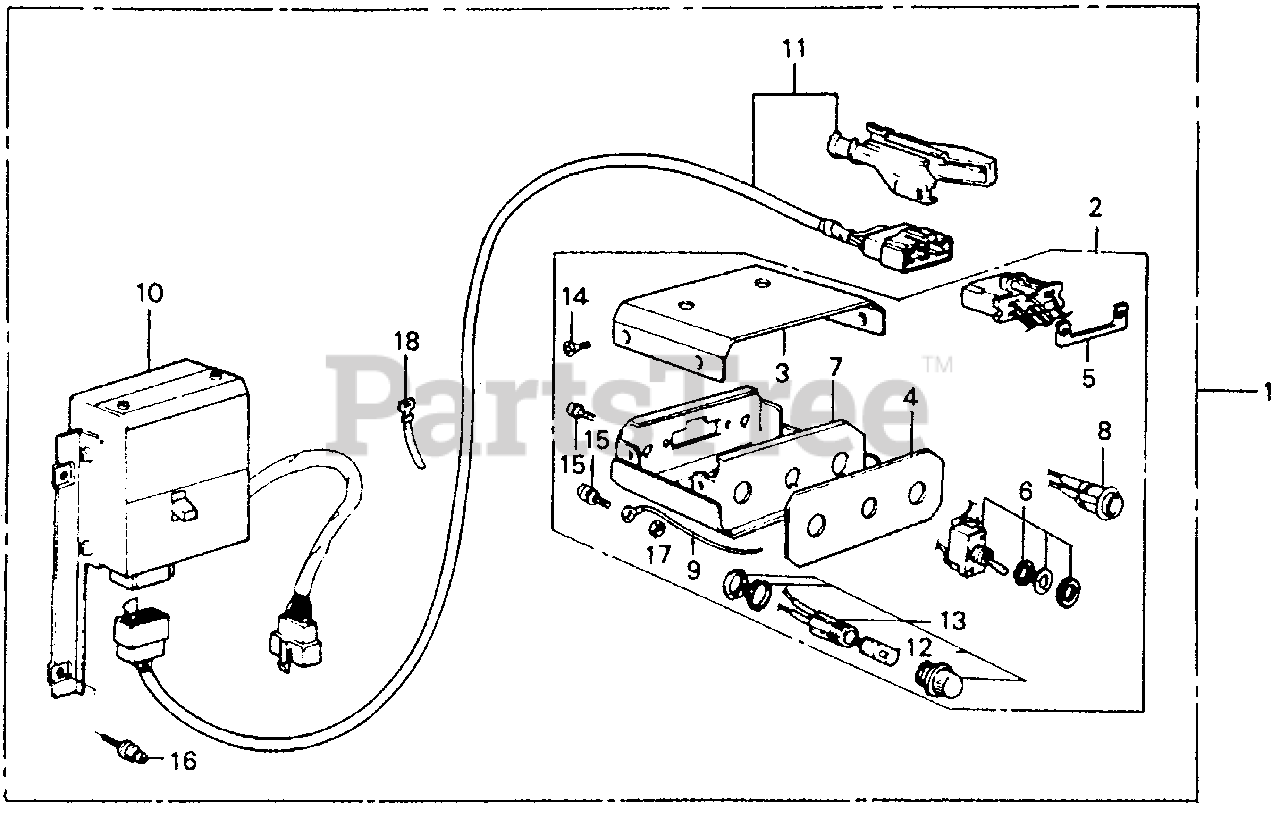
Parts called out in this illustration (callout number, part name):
1	CONTROL KIT, REMOTE
2	BOX ASSY., SWITCH *R8*
3	COVER (UPPER)
4	PANEL, FR.
5	PLATE, CONNECTOR SETTING
6	SWITCH, TOGGLE
7	CASE, SWITCH
8	SWITCH, PUSH
9	WIRE, GROUND
10	BOX ASSY., RELAY
11	CABLE, REMOTE CONTROL (10MM)
12	BULB (24V2W)
13	SOCKET ASSY., PILOT LAMP
14	SCREW, FLAT (4X8)
15	SCREW-WASHER (4X12)
16	SCREW-WASHER (6X25)
17	NUT, HEX. (4MM)
18	BAND B1, CABLE
